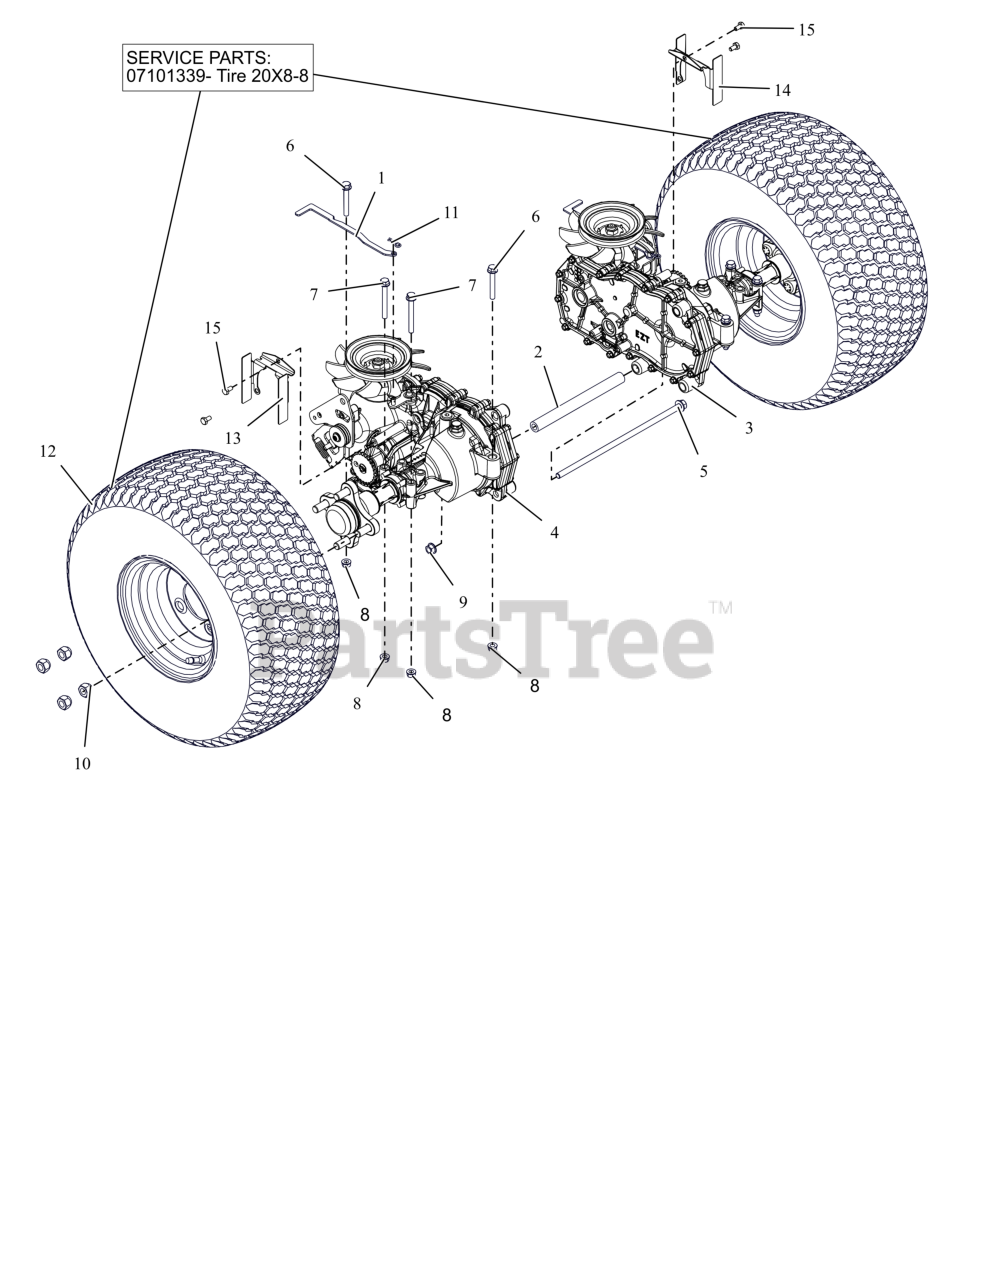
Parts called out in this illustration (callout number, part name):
1	BRKT, DUMP VALVE
2	TUBE, TRANSAXLE BRACE 8.18LG
3	TRANSAXLE
4	TRANSAXLE
5	BLT,HEX-FLG .38-16X11.5 G5 ZCC
6	BLT,HEX-FLG .31-18X2.25 G5 ZCC
7	BLT,HEX-FLG .31-18X2.75 G5 ZCC
8	NUT,LK-CTR-FLG .31-18 GF ZCC
9	NUT-LK-CTR-FLG .375-16 GF ZCC
10	NUT, WHEEL .50-20 ZCC
11	PIN, HAIR #213 .08X1.19 ZCC
12	ASSM TIRE\WHEEL, 20 X 8 -8
12	LAWN TIRE REAR, 4 PLY K505 20/8.00-8
12	VALVE STEM ASS'Y
12	TIRE TUBE 18/6.50/8.50/9.50-8, 20/8.00/10.00-8 4 PLY TR13 STRAIGHT VALVE
13	GUARD, PARKING BRAKE RH
14	GUARD, PARKING BRAKE LH
15	BLT,HEX .25-20X.50 G5 ZCC
